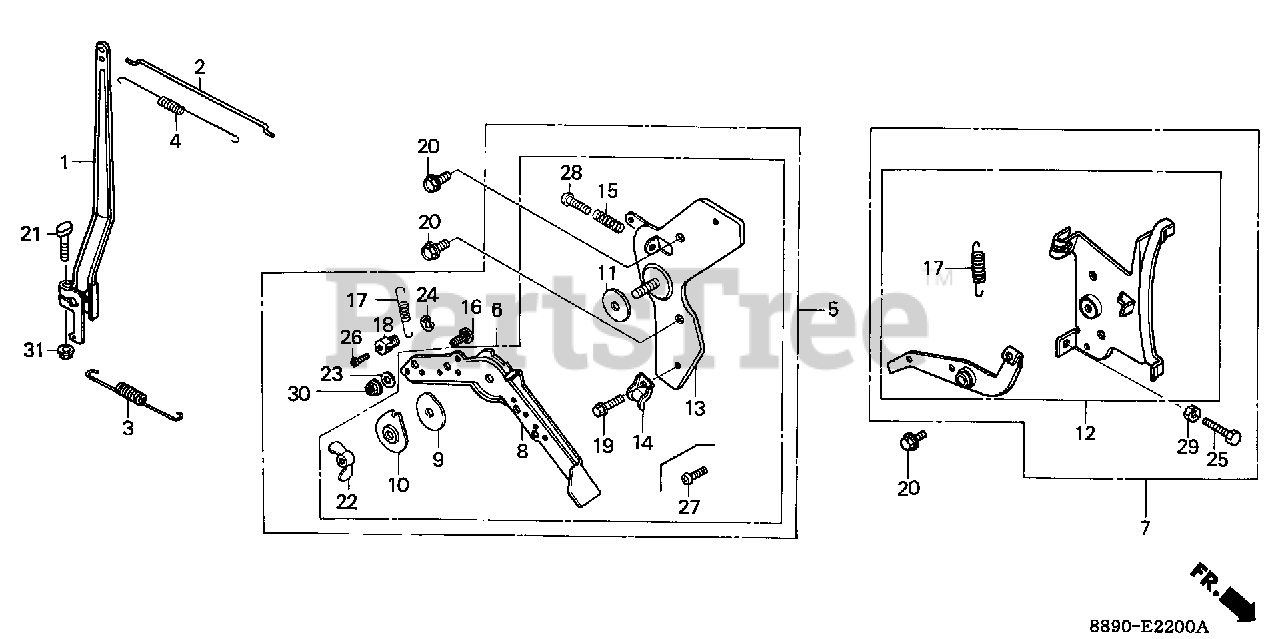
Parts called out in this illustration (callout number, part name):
1	ARM, GOVERNOR
2	ROD, GOVERNOR
3	SPRING, GOVERNOR (NOT AVAILABLE)
3	SPRING, GOVERNOR
4	SPRING, THROTTLE RETURN
4	SPRING, THROTTLE RETURN (NOT AVAILABLE)
5	CONTROL ASSY.
6	CONTROL ASSY.
8	LEVER, CONTROL
9	SPRING, LEVER
10	WASHER, CONTROL LEVER
11	SPACER, CONTROL LEVER
13	BASE, CONTROL LEVER
14	HOLDER, CONTROL CABLE
15	SPRING, CONTROL ADJUSTING
17	SPRING, CABLE RETURN
18	HOLDER, WIRE
19	BOLT, FLANGE (5X10)
20	BOLT, FLANGE (6X12) (CT200)
21	BOLT, GOVERNOR ARM
22	WINGNUT (6MM)
24	CIRCLIP (5MM)
26	SCREW, PAN (4X6)
27	SCREW, PAN (5X10)
28	SCREW, PAN (5X22)
31	NUT, FLANGE (6MM)
